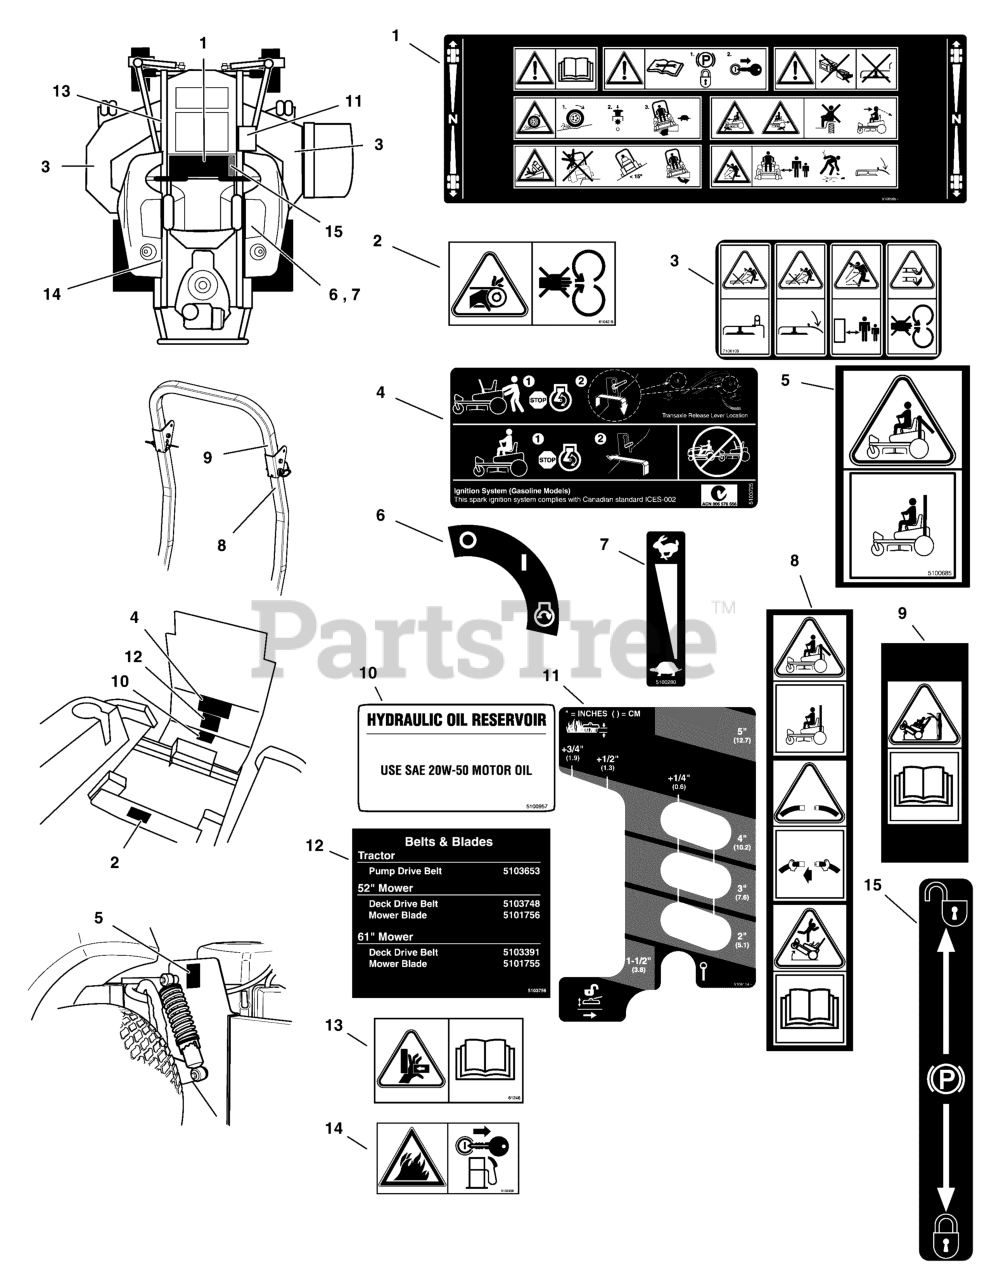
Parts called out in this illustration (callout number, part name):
1	DECAL, MAIN SAFETY, EXPORT
2	DECAL, CE DANGER
3	DECAL, DISCHARGE SAFETY, EXPORT
4	DECAL, TRANSAXLE RELEASE, 600/700
5	DECAL, WARNING, ROLL BAR, CE
6	DECAL, IGNITION SWITCH
7	DECAL, THROTTLE CONTROL
8	DECAL, SAFETY, CE ROPS
9	DECAL, SAFETY, CE ROPS, OBS
10	DECAL, HYDRAULIC OIL, SAE 20W50
11	DECAL, CUTTING HEIGHT
12	DECAL, BELT & BLADE, IS700Z/ZTS700
13	DECAL, PINCH POINT, CE
14	DECAL, FIRE ANSI EXPORT
15	DECAL, PARKING BRAKE SYMBOLS
